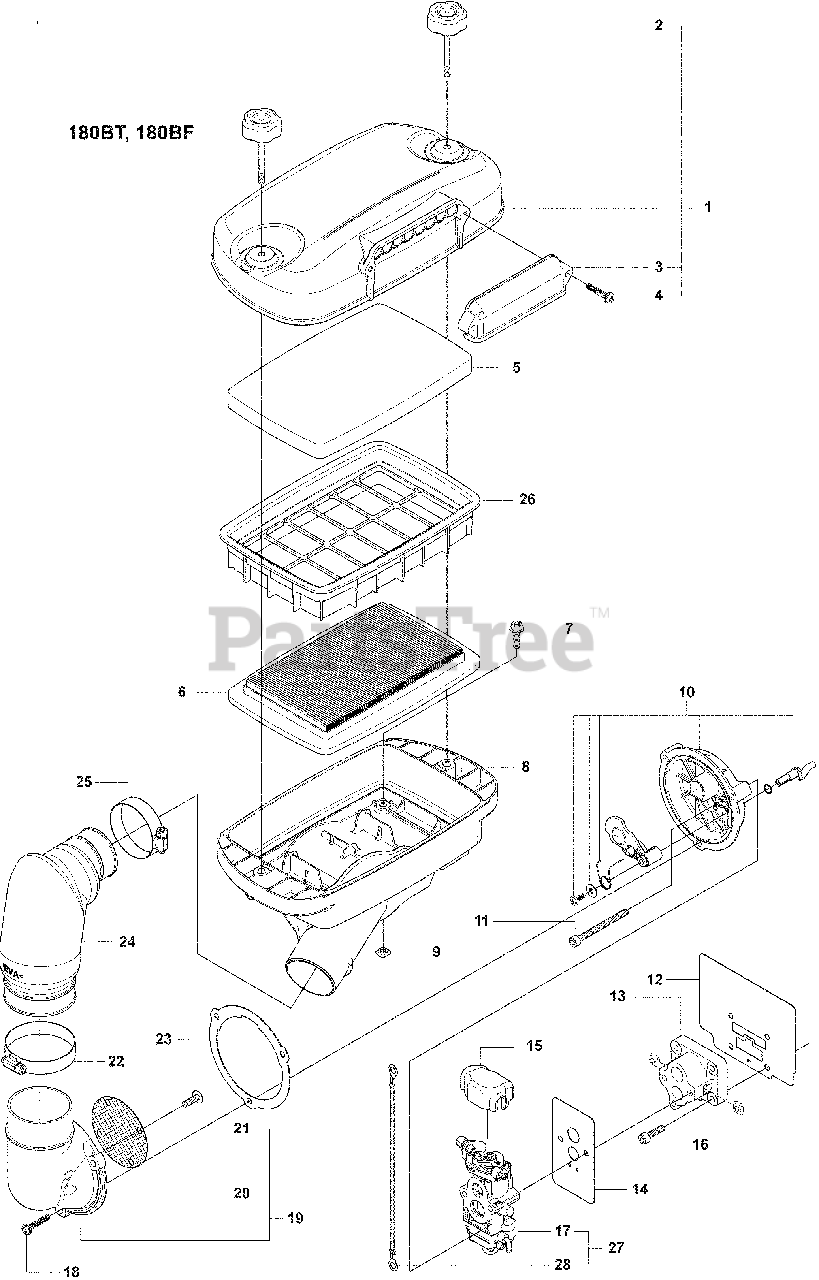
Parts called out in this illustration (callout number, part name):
1	Cover Assembly
4	Screw
5	Air Filter Element
6	Air Filter Element
7	Bolt
10	Cup Assembly
11	Bolt
12	Gasket
13	Insulator
14	Gasket
15	Cover
16	Bolt
17	Carburetor Assembly
18	Screw
19	Cup Cover Assembly
21	Screw
22	Clamp, F64
23	Gasket
25	Clamp, F64
27	Carburetor Set
28	CORD
